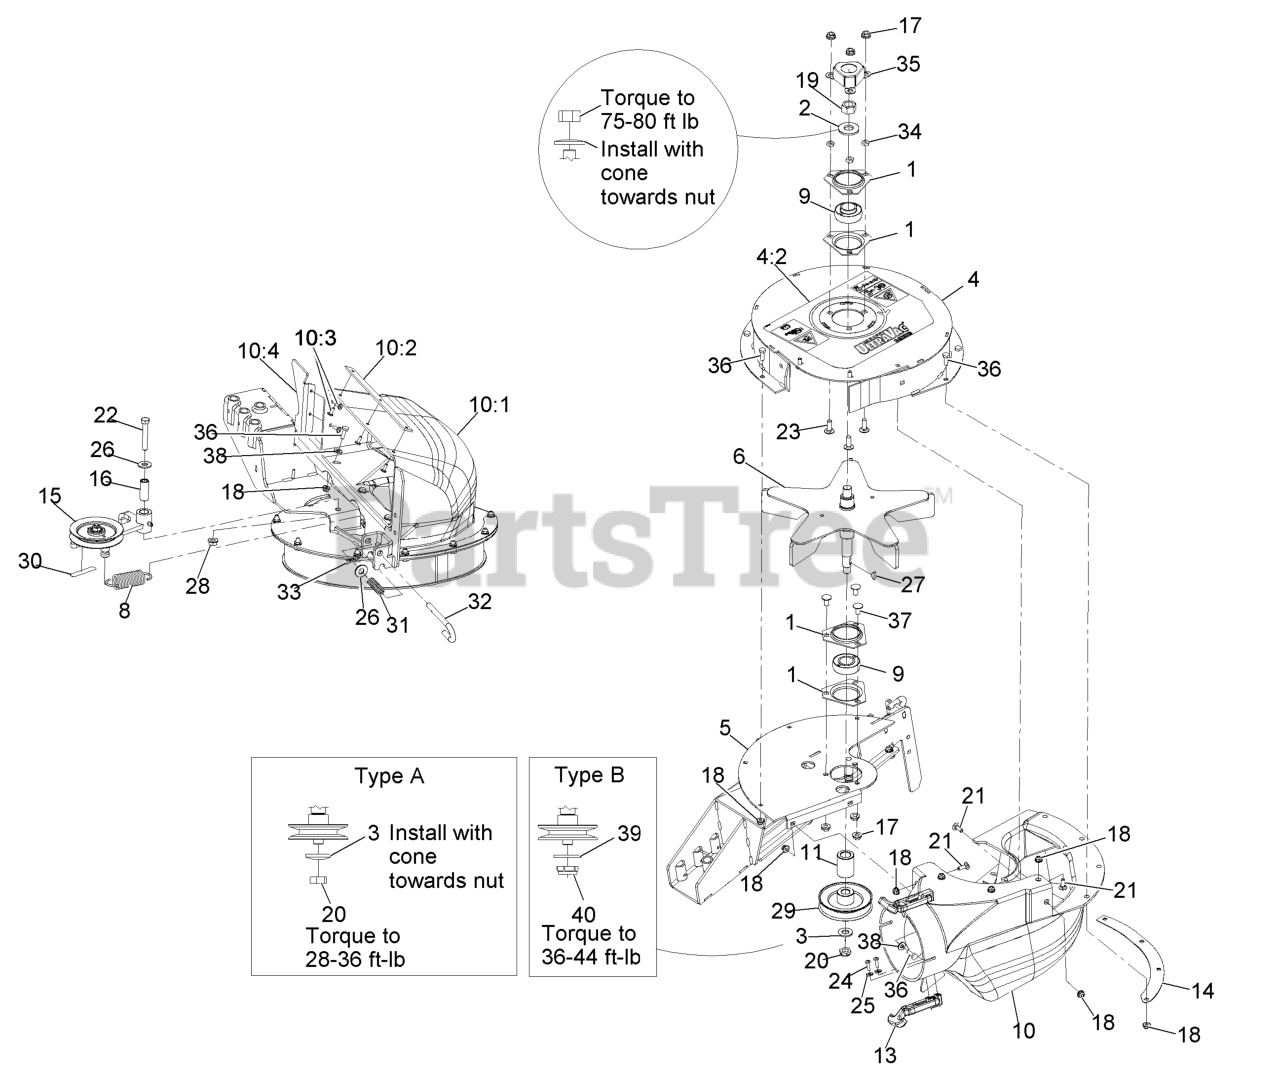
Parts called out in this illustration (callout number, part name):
1	HOUSING-FLANGE
2	WASHER-SPRING
3	WASHER-FLAT
4	UPPER HOUSING W/DECAL
4:2	Decal-Blower Warning
5	BLOWER FRAME ASM
6	IMPELLER
8	SPRING-IDLER
9	BEARING
10	BLOWER CHUTE ASM
10:1	CHUTE-BLOWER, SMALL
10:2	PLATE-REINFORCEMENT
10:3	RIVET-BLIND
10:4	PLATE-FILLER
13	LATCH-RUBBER
14	PLATE-BACKING
15	ASM, Idler
16	BUSHING
19	NUT-HEX
20	NUT-LOCK, NI
21	BOLT-CARR
22	SCREW-HH
23	BOLT-CARR
24	SCREW-PPH
25	WASHER-FLAT
26	WASHER-FLAT
27	KEY-WOODRUFF
28	NUT-HHF, WHIZ
29	SHEAVE-BLOWER
30	DECAL-WARNING
31	SPRING-COMPRESSION
32	PIN-LATCH
34	NUT-JAM
35	COVER-NUT
36	SCREW-HH
37	SCREW-CARR
38	WASHER-FLAT
39	WASHER-FLAT
40	NUT-LOCK, NI
